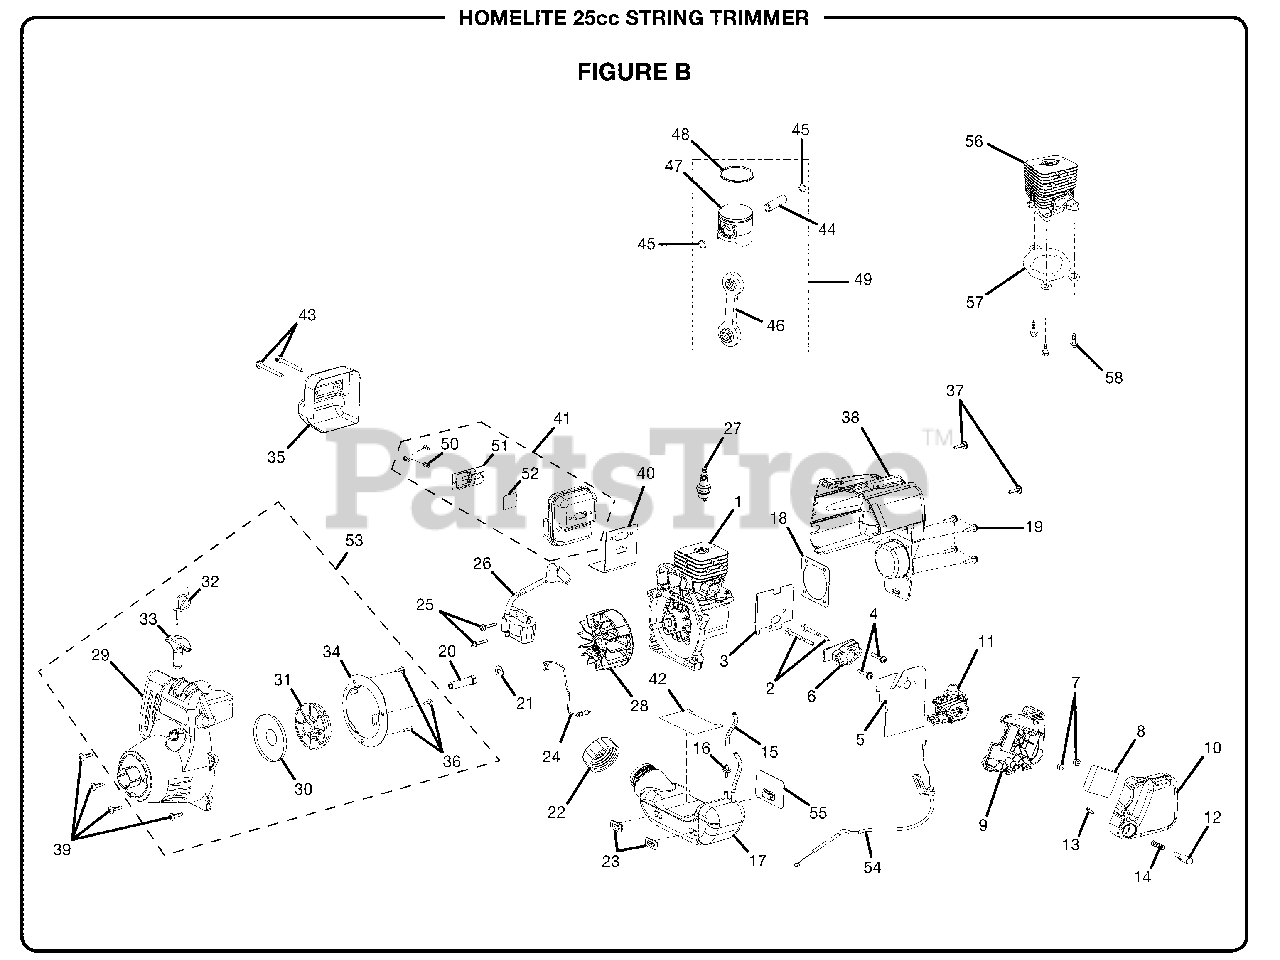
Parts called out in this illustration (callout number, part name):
1	SHORT BLOCK ASSEMBLY
2	CARBURETOR BOLTS
3	INTAKE GASKET
4	SCREW (10-24 X 1-1/16 IN. PAN HD.)
5	CARBURETOR GASKET
6	HEAT DAM
7	LOCK NUT (10-24)
8	AIR FILTER
9	AIR FILTER BOX
10	AIR BOX COVER
11	CARBURETOR ASSEMBLY
12	BUTTON SWITCH
13	SCREW, (6-19 X 1/2 IN. T.F.)
14	COMPRESSION SPRING
15	RUBBER TUBING (2 IN.)
16	INLINE FUEL FITTING
17	FUEL TANK
18	CRANK CASE COVER GASKET
19	SCREW (10-24 X 3/4 IN. PAN HD. TORX W/LW)
20	DRIVE CONNECTOR
21	FLAT WASHER
22	FUEL CAP ASSEMBLY
24	LEAD W/TERMINALS
25	SCREW (8-32 X 1 IN. THREAD FORMING)
26	IGNITION MODULE
27	SPARK PLUG
28	ROTOR AND PAWL ASSEMBLY
29	STARTER HOUSING ASSEMBLY
30	SPRING AND CONTAINER
31	STARTER PULLEY
32	STARTER ROPE
33	STARTER GRIP
35	HEAT SHIELD
36	SCREW (8-16 X 1/2 IN. THREAD FORMING)
37	SCREW (10-14 X 3/4 IN.THREAD FORMING)
38	REAR HOUSING
39	SCREW (10-24 X 3/4 IN.TRUSS HD.)
40	MUFFLER GASKET
41	CATALYTIC MUFFLER ASSEMBLY
43	SCREW (10-24 X 2-3/16 IN. TORX HD.)
44	PIN, PISTON
45	CLIP RING
46	CONNECTING ROD ASSEMBLY
47	PISTON, 25CC
48	PISTON RING
49	PISTON ASSEMBLY
50	SCREW (6-20 X 1/4 IN. PAN HD.)
51	OUTLET TUBE
53	COMPLETE STARTER ASSEMBLY
54	THROTTLE CABLE W/HANGER
55	BUMPER
56	CYLINDER
57	CYLINDER GASKET
58	SCREW (10-24 X .66 IN TORX PAN HD.)
